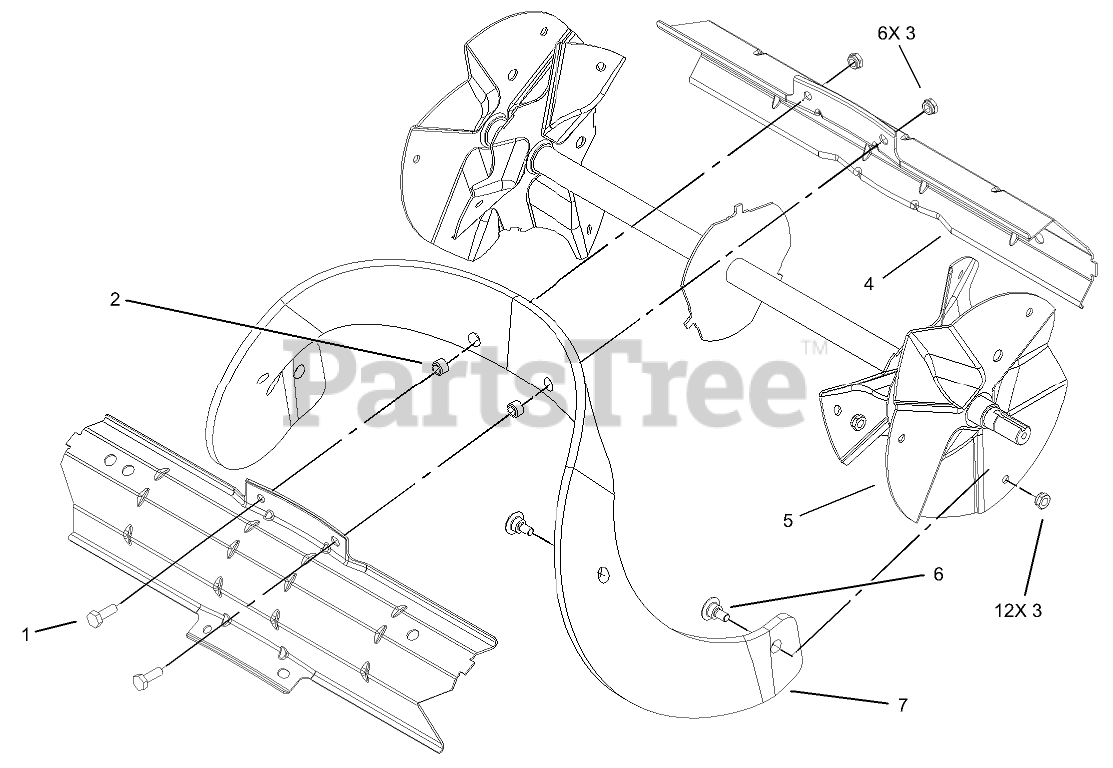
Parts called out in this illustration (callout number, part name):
1	SCREW-HH
2	SPACER-BLADE, ROTOR
3	NUT-LOCK, NI
4	DRUM-ROTOR
5	ROTOR ASM
6	SCREW
7	BLADE-ROTOR
